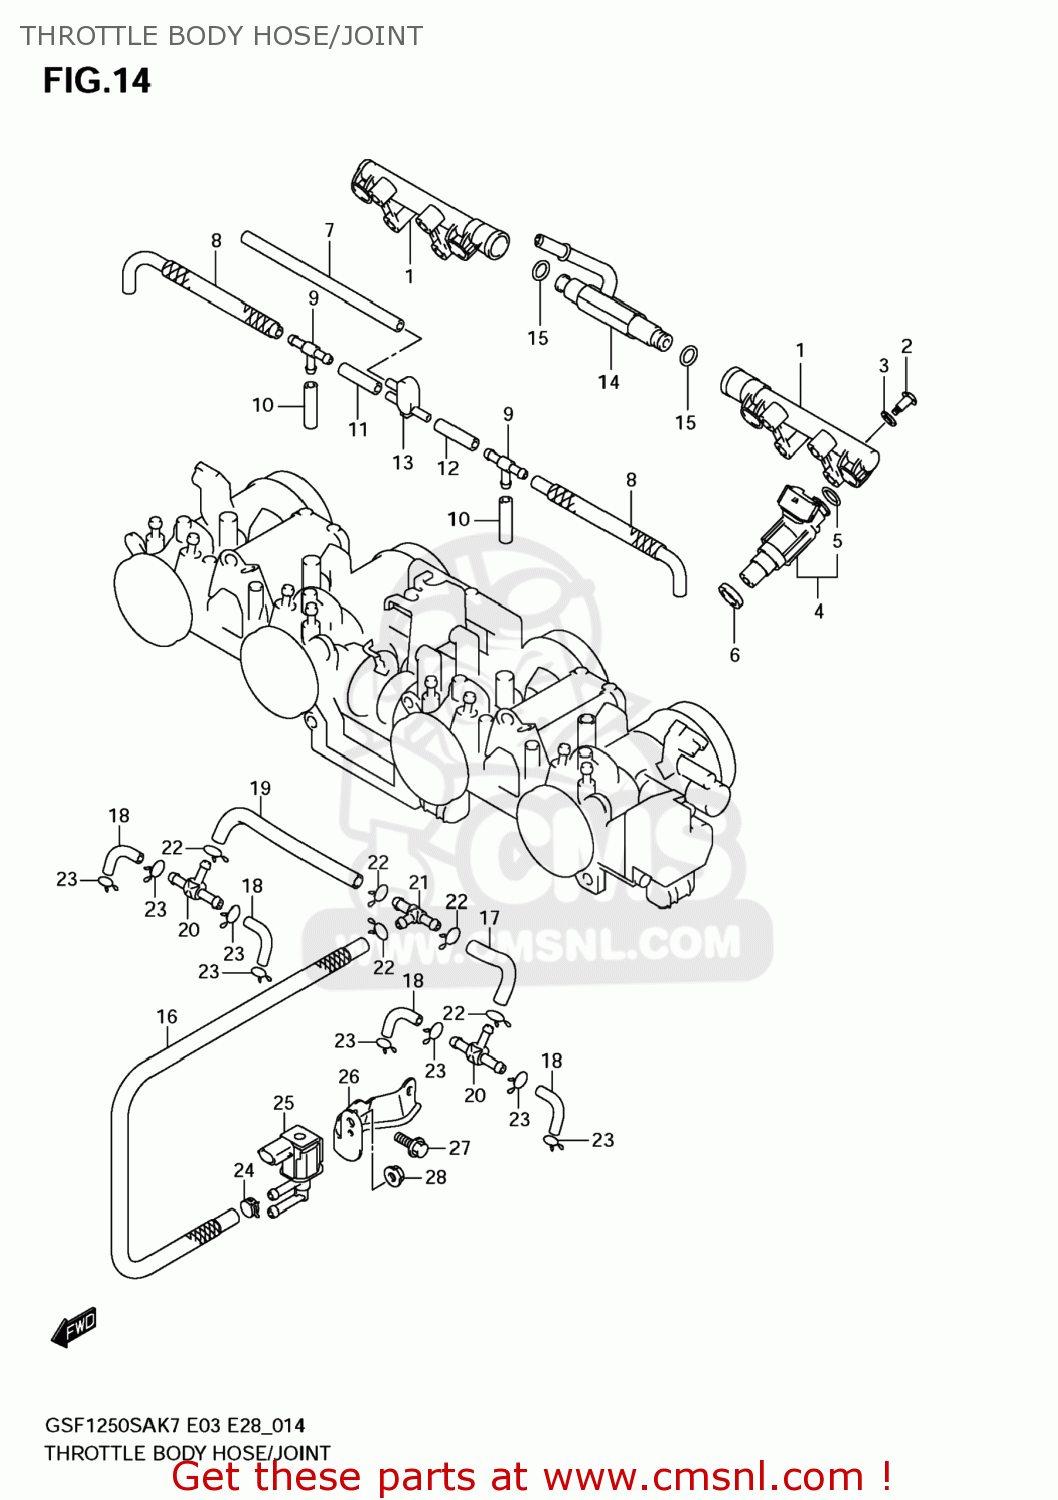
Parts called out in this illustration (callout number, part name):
1	DELIVERY PIPE
2	SCREW
3	PACKING (NAS)
4	INJECTOR ASSY
5	O RING
6	SEAL
7	HOSE
8	HOSE
9	3WAY,VACUUM HOSE
10	HOSE
11	HOSE
12	HOSE
13	JOINT
14	NIPPLE
15	O RING
16	HOSE
17	HOSE
18	HOSE
19	HOSE
20	NIPPLE
21	NIPPLE
22	CLIP
23	CLIP
24	CLIP
25	VALVE,CANISTER PURGE
26	BRACKET COMP,SOLENOID VALVE
27	BOLT
28	NUT
